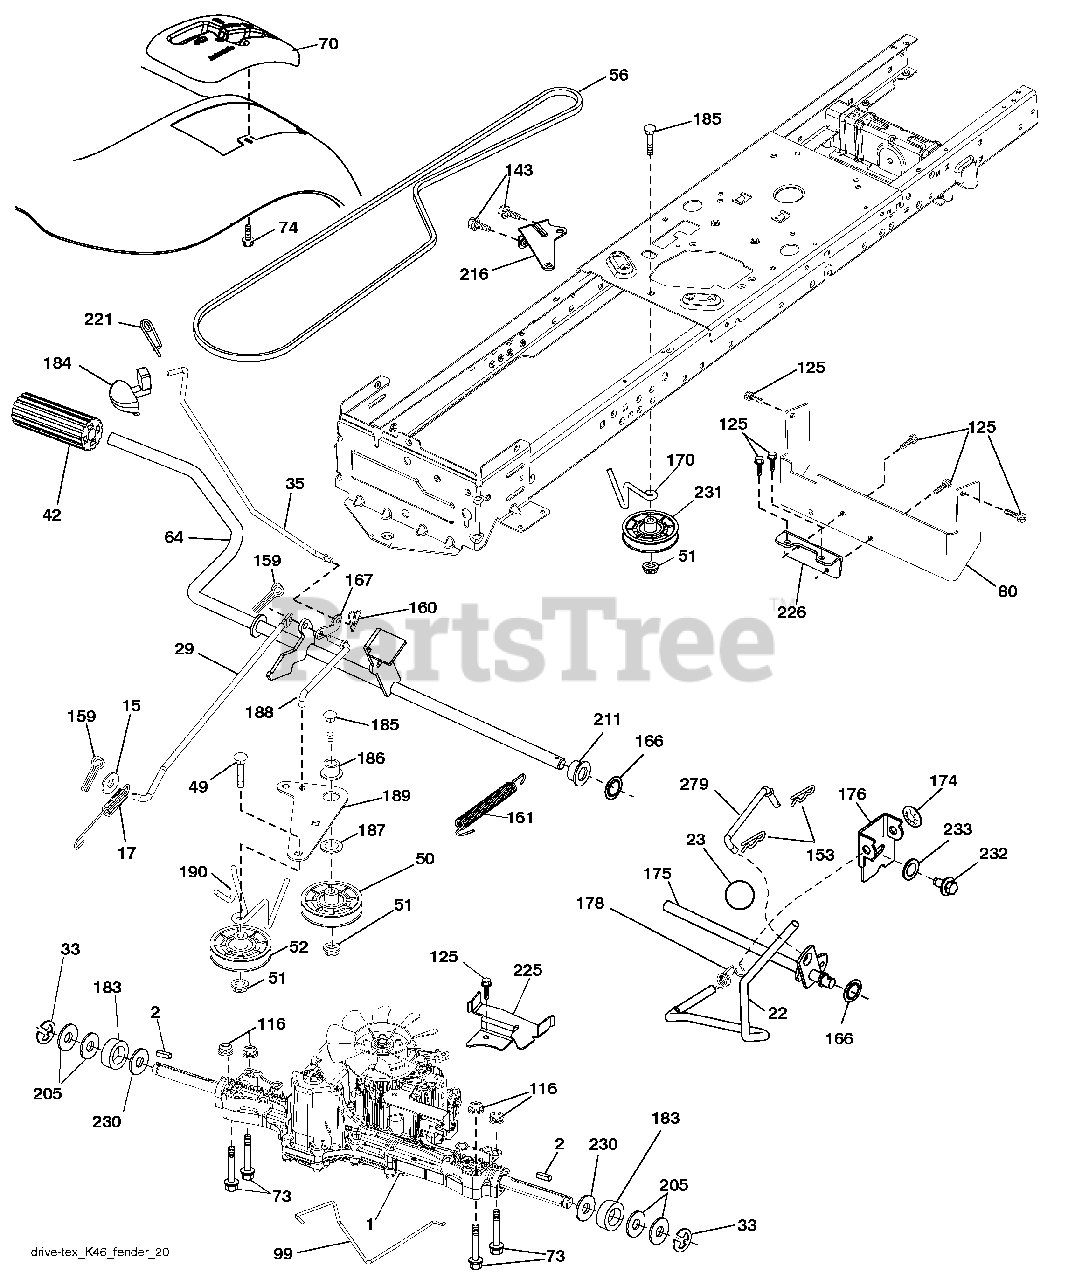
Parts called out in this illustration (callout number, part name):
2	Key
15	Washer 13/32 x 13/16 x 16 Ga.
17	Spring, Brake
22	Rod Shift
23	Knob Deluxe
29	Rod, Brake
33	Ring E
35	Rod, Brake, Park
42	Cover, Foot Pedal
49	Bolt
50	Pulley Idler Flat
51	Lock Nut 3/8-16
52	Idler V-Groove 910" Offset
56	V-Belt, Drive
64	Shaft Asm. Pedal Brake Control
70	Console Shift
73	Bolt Hex Flghd 5/16-18 Gr. 5
74	Screw Hex Wsh Hi-Lo 1/4 x 1/2 unc
80	Strap Torque
99	Rod Spring Bypass
116	Nut Lock Hex Flange 5/16-18
125	Screw 5/16-18 x 3/4
143	Screw 5/16-18 x 1/2
153	Retainer Spring
159	Pin Cotter 1/8 x 3/4
160	Retainer Clip
161	Spring, Return, Clutch
166	Nut Push
167	Latch Brake Parking
170	Keeper Belt Centerspan
174	Nut Push
175	Shaft Asm. Shift
176	Arm Clevis Rod Shift
178	Spring Shift
183	Spacer Axle
184	Handle Parking Brake
185	Bolt
186	Spacer Retainer
187	Washer
188	Link Clutch Ground Drive
189	Bellcrank Ground Drive
190	Keeper Bellcrank Ground Drive
205	Washer 25/32 x 1-5/8 x 16 Ga.
211	Bearing Shaft Brake
216	Bracket Pulley Idler
221	Retainer Spring Clip Handle
225	Keeper Belt Transaxle
226	Bracket Mount Torque
230	Washer Hardened
231	Idler V-Groove
232	Bolt fin Hex 7/16-14 x 1 Gr. 5
233	Washer Serrated
279	Link Shift T/A
